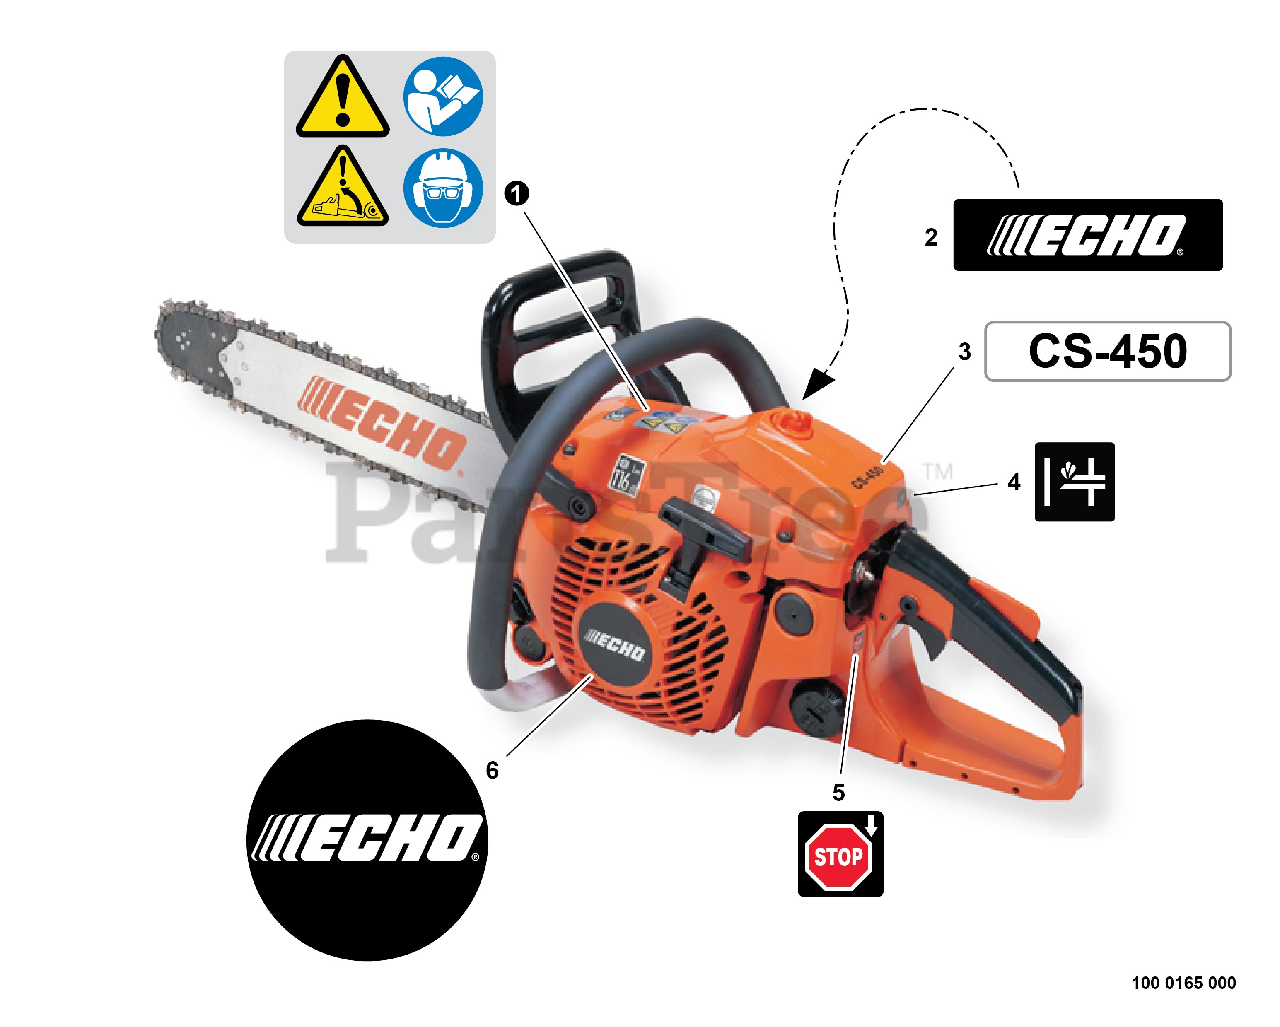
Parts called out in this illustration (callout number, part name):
1	LABEL - CAUTION
2	LABEL - ECHO
3	LABEL - MODEL CS-450
4	LABEL - PURGE PUMP
5	LABEL - STOP
6	LABEL - ECHO
